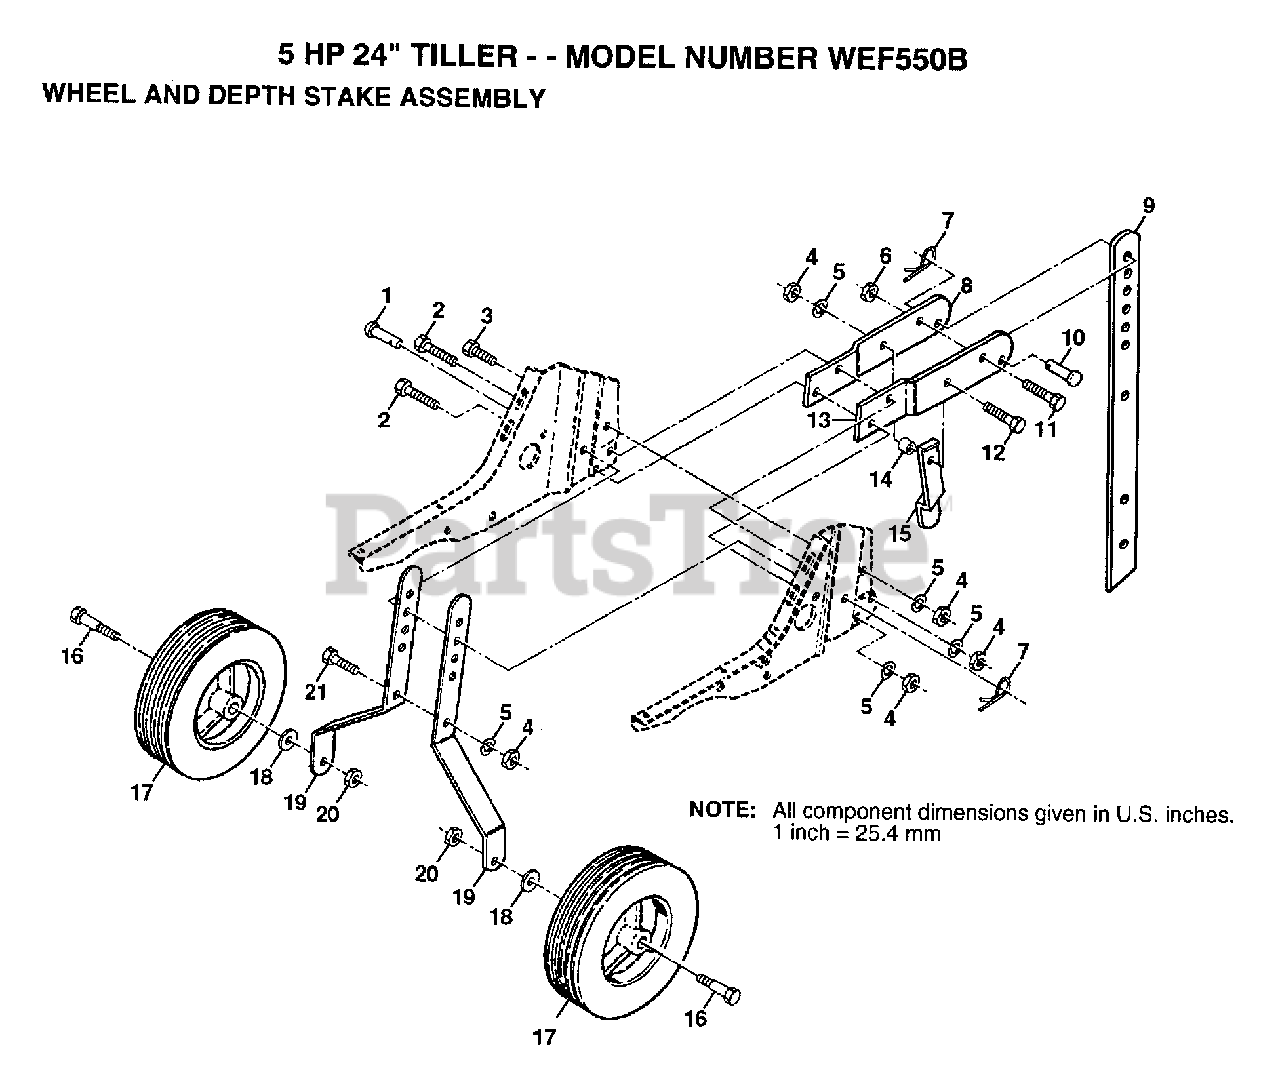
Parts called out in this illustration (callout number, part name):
1	DRILLED RIVET RT
3	BOLT
4	NUT.HEX.5/16-18
5	LOCKWASHER
6	GRIPCO NUT
7	SPRING.RETAINER
11	BOLT.3/8-24X1-1/2
12	BOLT.HEX.5/16-1.5
14	WASHER
15	STAKE SPRING TI
16	BOLT SHOULDER
18	WASHER
